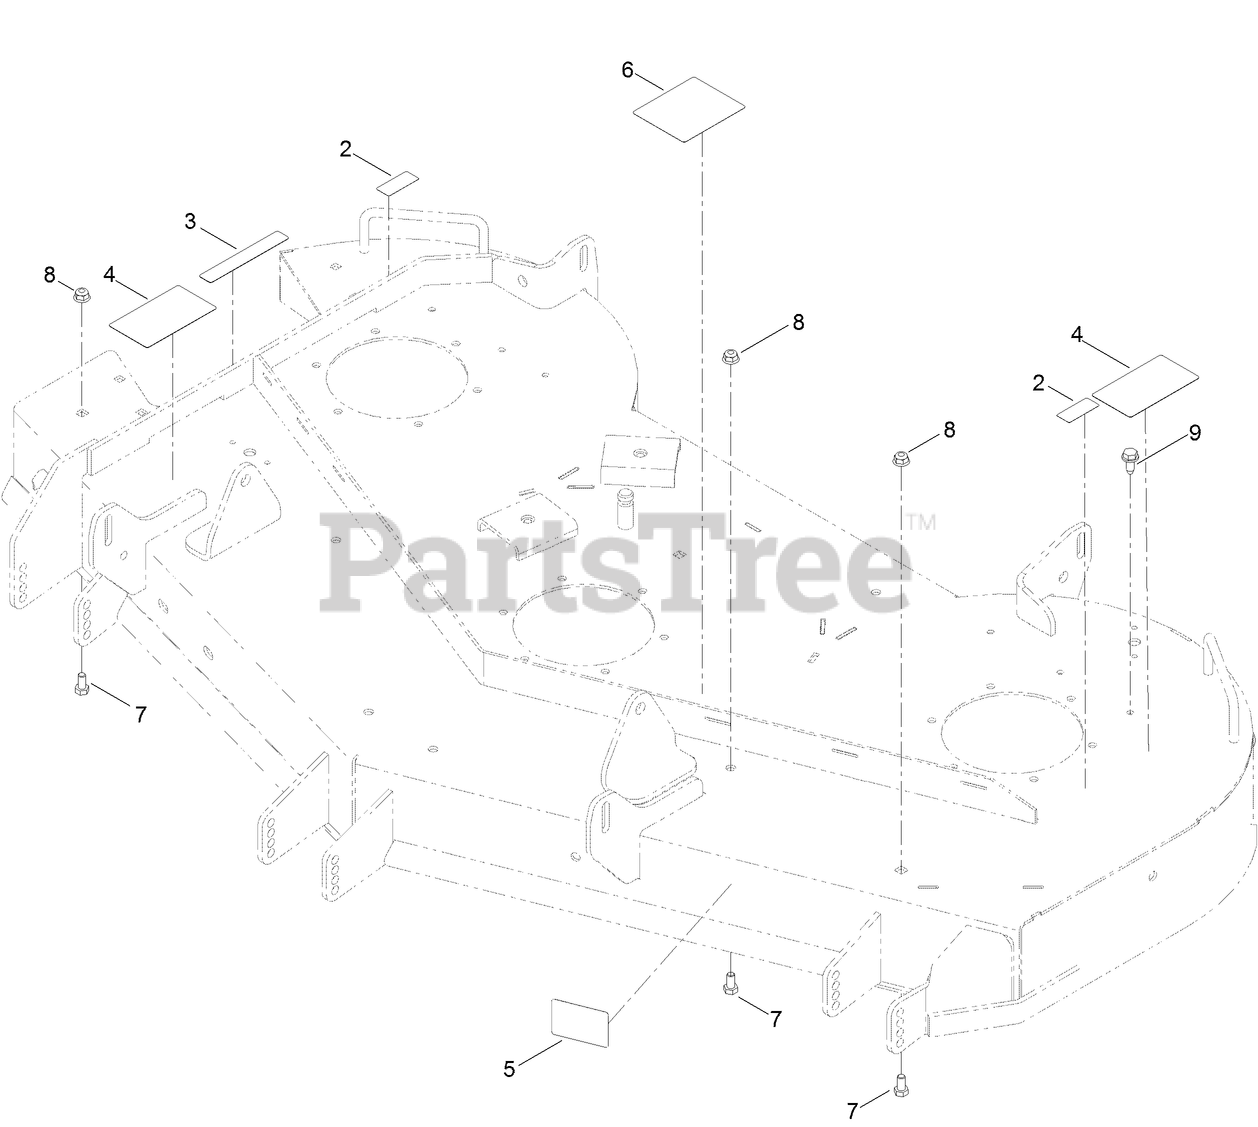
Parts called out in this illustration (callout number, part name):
2	DECAL-DANGER
3	DECAL-DANGER
4	DECAL-DANGER
5	DECAL-SCALP, ANTI
6	DECAL-ROUTING, BELT
7	SCREW-HH
8	NUT-HF, NI
9	SCREW-HWHTF
